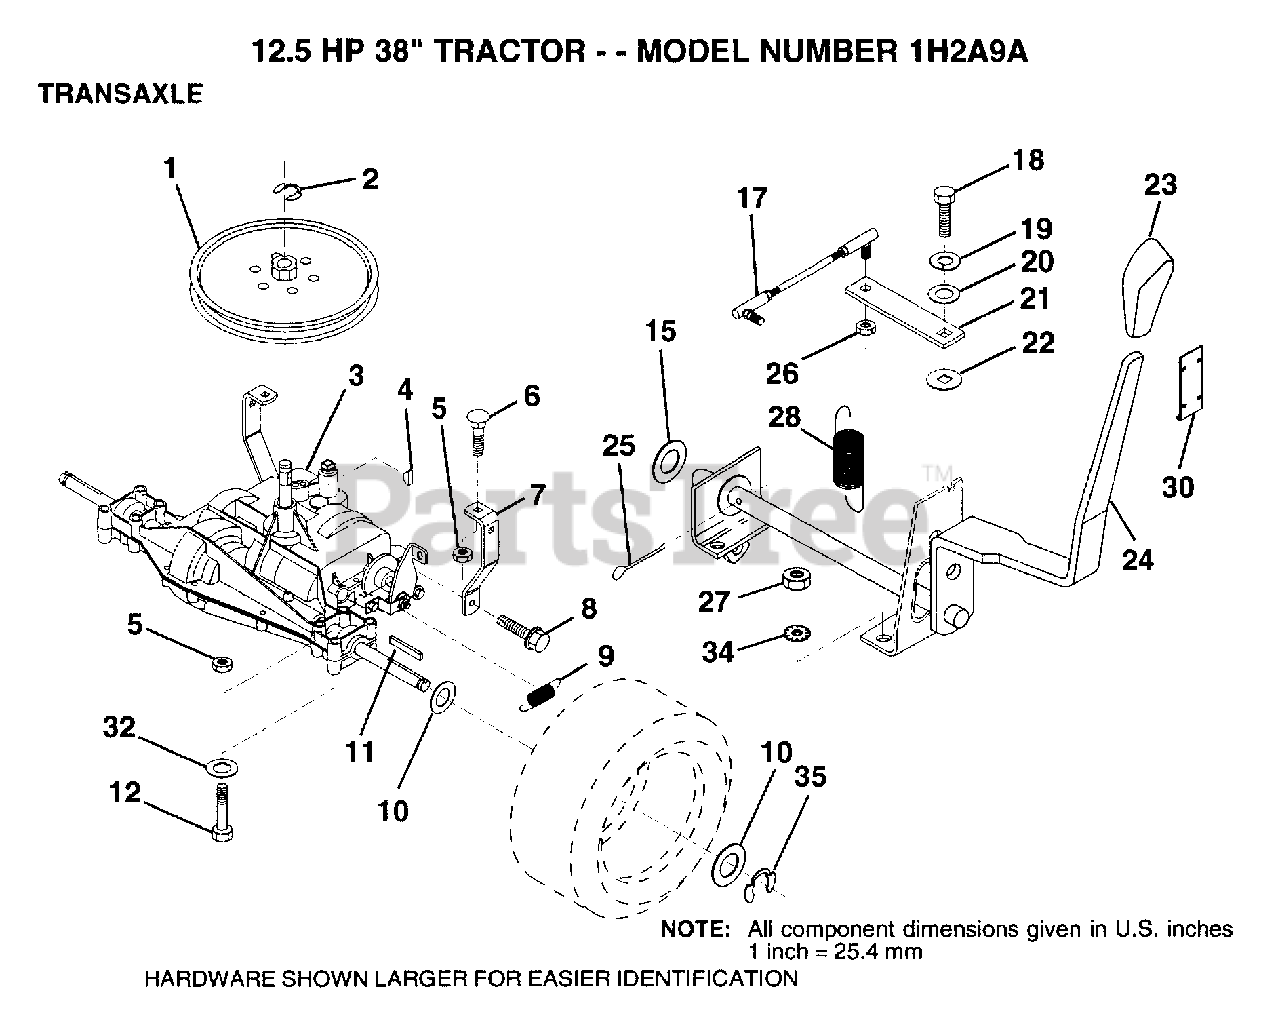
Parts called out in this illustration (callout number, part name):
1	PULLEY
6	BOLT
7	"STRAP,TORQUE"
8	SCREW
10	WASHER
11	SQUARE KEY
12	BOLT
17	LINK SHIFT
19	LOCKWASHER
20	WASHER LT
22	WASH-SHFT PLT LT
23	"KNOB,SHT CONTROL"
25	PIN COTTER 1/8
26	NUT.LOCK.5/16-24
28	"SPRING,EXT"
30	KNOB RETAINER
32	WASHER
34	LOCKWASHER.5/16.E
35	E-RING LT
